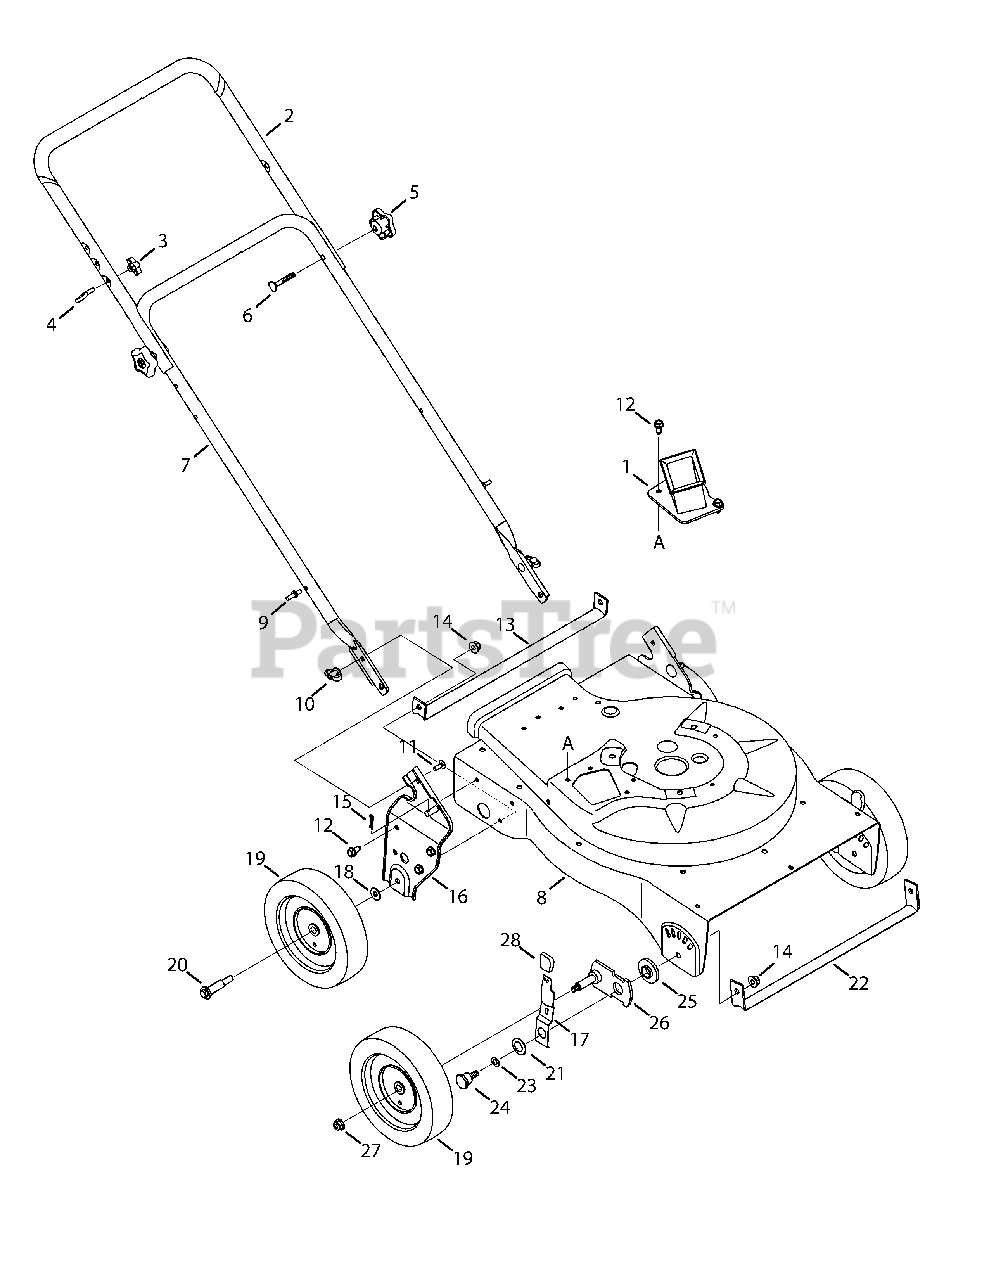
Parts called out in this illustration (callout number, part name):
1	Chipper Chute Assembly
2	Upper Handle
4	Eye Bolt
5	Star Knob, 5/16-18
6	Carriage Bolt
7	Lower Handle
8	Upper Housing
9	Studs
10	Wing Nut 1/4-20
11	Carriage Screw 1/4-20 x.75
12	Screw, 5/16-12 x.750
13	Rear Wheel Support Brace
14	Flange Lock Nut, 3/8-16
15	Cotter Pin
16	Handle Bracket Assy. LH
17	Spring Lever
18	Bell Washer.401 ID x.870 OD
19	Wheel, 8 x 1.8, Bar
20	Shoulder Screw 3/8-16
21	Bell Washer.760 ID x.25OD
22	Front Wheel Support Brace
23	Thrust Washer.375 ID x.70 OD
24	Shoulder Screw, .750 ID x .500
25	Height Adjustment Bearing
26	Pivot Arm Assembly
27	Flange Lock Nut, 3/8-16
28	Height Adjustment Knob
